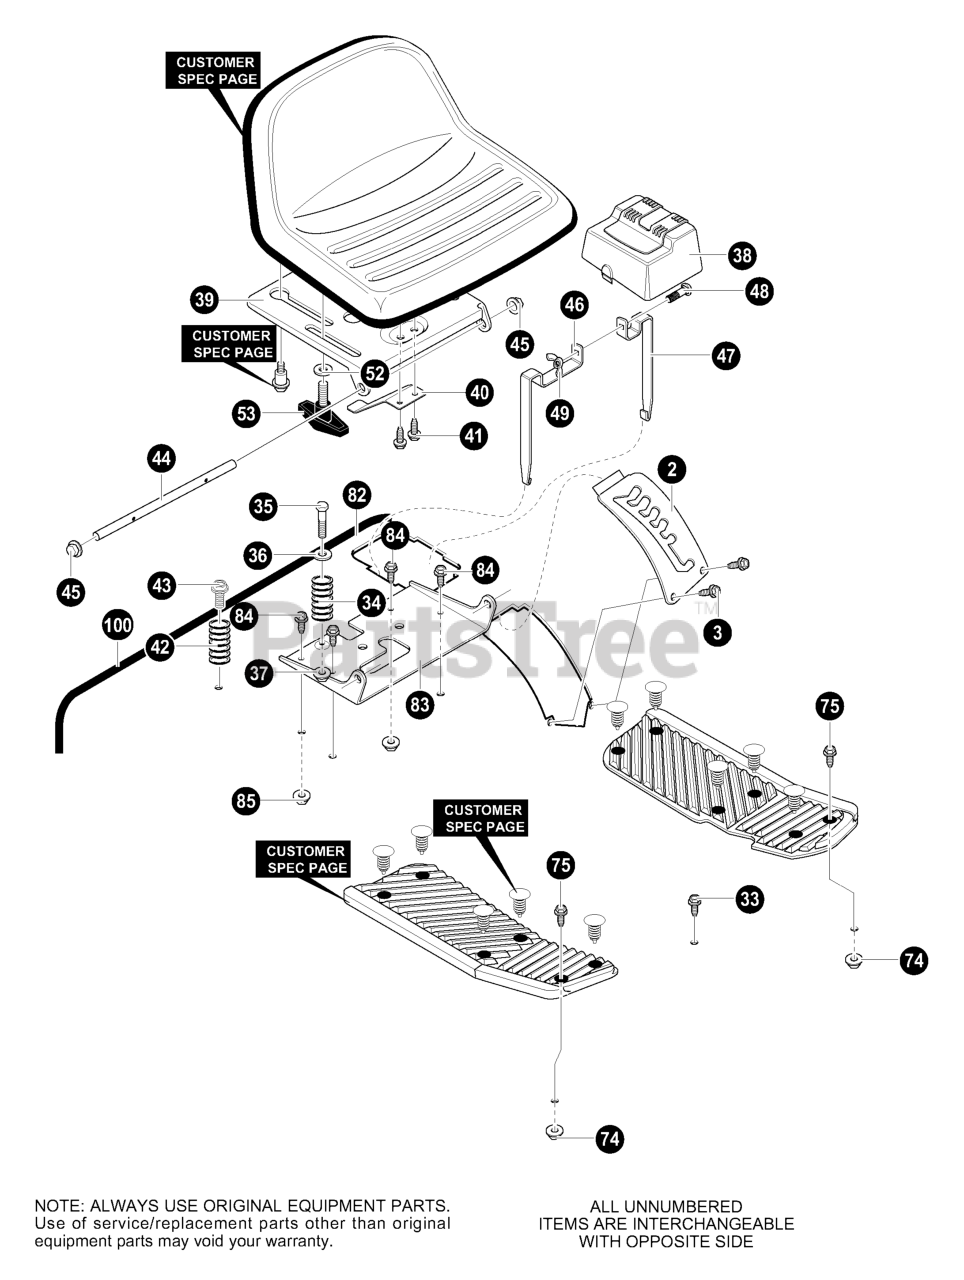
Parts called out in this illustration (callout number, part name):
2	PLATE, LIFT DETENT
3	SCREW, #12X.50 PHPNHTAP
33	SCREW, 5/16-18 x .75 HHWATAP
34	SPRING, COMPRESSION 4.57LGX1.17
35	BOLT, SHOULDER 1/4-20
36	ZINC WASHER CUP
37	NUT, 1/4-20 CENTERLOCK
38	COVER, BATTERY
39	SUPPORT, SEAT
40	SPRING - LEAF
41	SCREW, 1/4-20X.50 WAHHTAP
42	SPRING, COMPRESSION 2.43LG 164X30
43	SCREW, 5/16-18 x 0.75 HHWATAP
44	ZINC HINGE SEAT PIVOT
45	NUT, PUSH CAP .375
46	BATTERY, BRACKET L.H.
47	BATTERY BRACKET R.H.
48	BOLT, 1/4-20X.63 CARR.
49	NUT, WING 1/4-20 14X79
52	WASHER, FLAT .344X.62X.06
53	BOLT, WING 5/16-18X.50
74	NUT, 5/16-18 HEXWDFLLK WHIZ
75	BOLT, 5/16-18X.7A5 CARR.
82	SEAT DECK PEDAL HYDRO
83	BRACKET, PIVOT SEAT
84	SCREW, 5/16-18 x 0.75 HHWATAP
85	NUT, 5/16-18 WDFLLK
